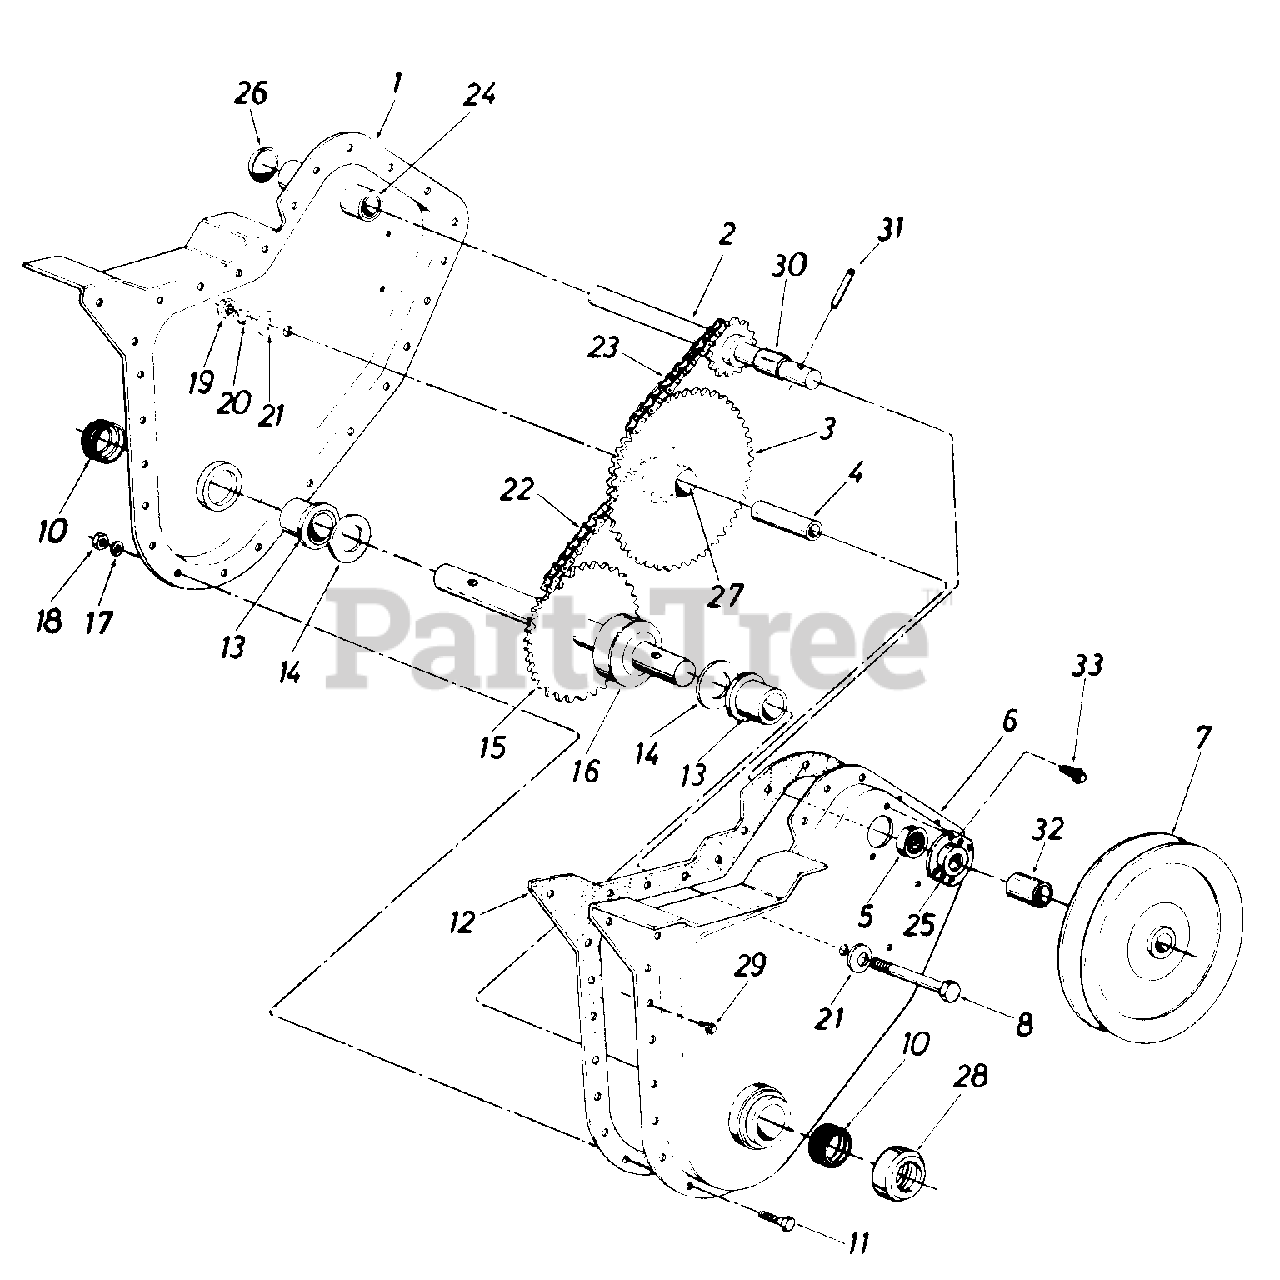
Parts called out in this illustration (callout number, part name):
1	Chain Case Ass'y.-R.H.
2	Input Shaft Ass'y.
3	Hub and Sprocket Ass'y.
4	Bearing Inner Race
5	Ball Bearing
6	Chain Case Ass'y.-L.H.
7	Pulley-Chain Case 5 1/2 x 1/2
8	Hex Bolt 3/8-24 x 2.50" Lg.
11	Hex Bolt 1/4-28 x .625" Lg.
12	Gasket
13	Flange Brg. .879 I.D.
14	Fl-Wash. .88 I.D. x 1.50 O.D. x .030
15	Tine Shaft Ass'y.
16	Spacer 7/8" I.D. x 2.0" O.D. x.68" Lg.
17	L-Wash. 1/4" I.D.*
18	Hex Nut 1/4-28 Thd.*
19	Hex Ins. L-Nut 3/8-24 Thd.
20	L-Wash. 318" I.D.*
21	Bell-Wash. .406 I.D. x 1.130 O.D
22	Chain #420-.50" Pitch x 38 Links
23	Chain #35-.375" Pitch x 50 Links
24	Bearing .62" I.D. x .813 O.D. x 1.31
25	Bearing Housing
26	Expansion Plug 13/16" Dia.
29	Hex Wash. Hd. Self-Tap Scr. 1/4-2O x .50" Lg.
30	Spacer .630" I.D. x .77" O.D. x.38" Lg.
31	Spring Pin Spiral 1/4" Dia. x 1-1/2 " Lg.
32	Spacer .647 x 1.25
33	Hex Wash. Hd. Self-Tap Scr. 1/4-20 x .38" Lg.
